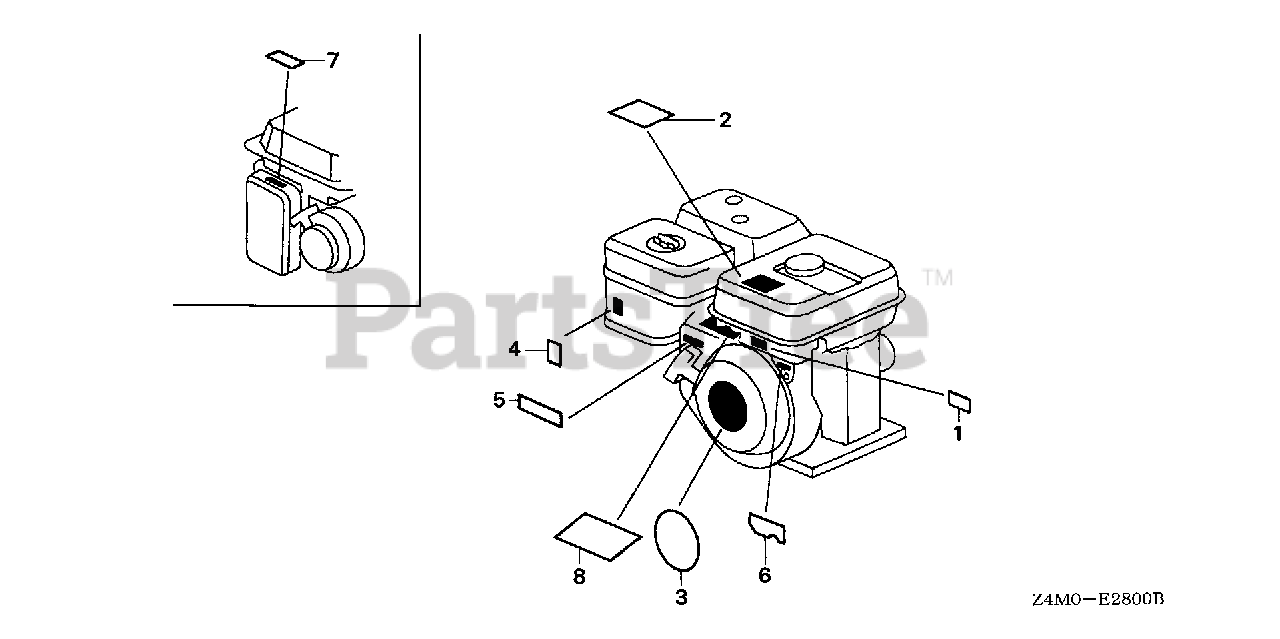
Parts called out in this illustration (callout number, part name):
2	MARK, OPERATOR CAUTION (Honda Code 8018954). (ENGLISH)(MADE IN THAILAND)
2	MARK, OPERATOR CAUTION (Honda Code 8018962). (FRENCH)(MADE IN THAILAND)
2	MARK, OPERATOR CAUTION (Honda Code 8018970). (PICTOGRAPH)(MADE IN THAILAND) (NOT AVAILABLE)
3	EMBLEM (5.5)
4	MARK, CHOKE
5	MARK, THROTTLE INDICATION
